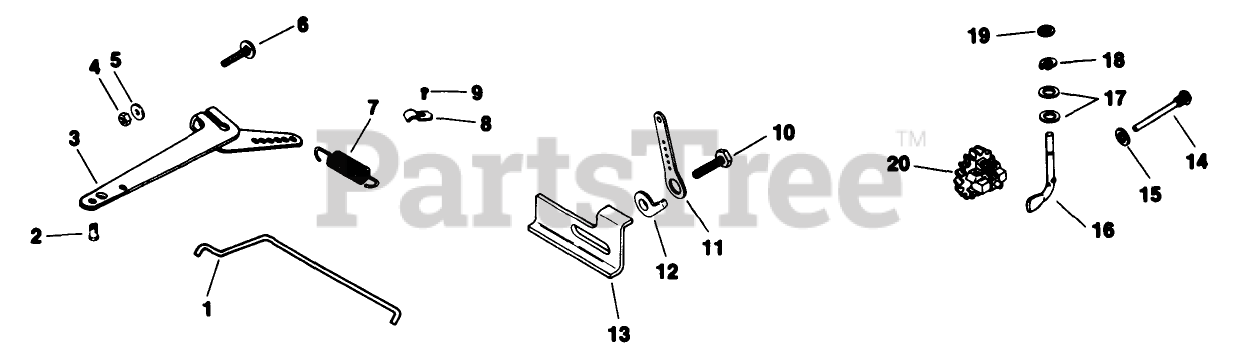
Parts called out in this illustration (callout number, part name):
1	Linkage-Governor
2	Bushing-Linkage (Yellow)
3	Arm-Governor
5	Washer
6	Screw-Round Hd.
7	Spring-Governor
8	Clip
9	Screw
10	Screw-H.C
11	Lever-Speed Control
12	Stop-Govenor
13	Stop-High Speed
14	Pin-GovemorStop
15	Washer
16	Shaft-Govenor
17	Washer
18	Retainer-Governor
19	Washer
20	Governor Gear
